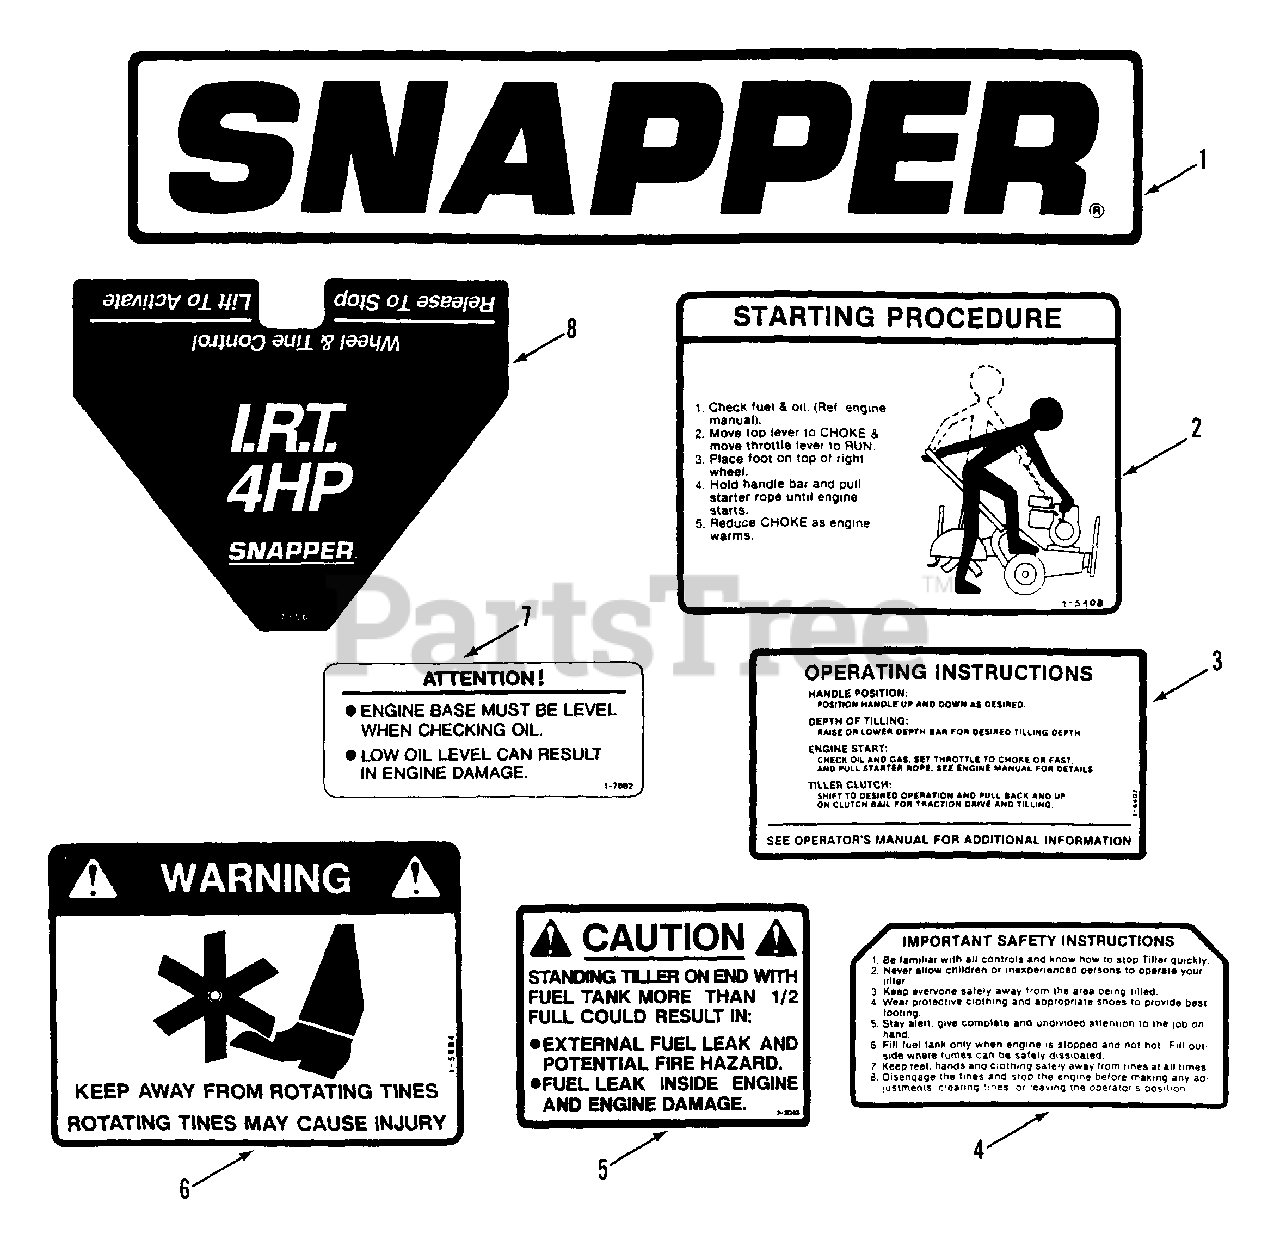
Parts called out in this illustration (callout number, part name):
1	DECAL, SNAPPER
2	DECAL, Starting
3	DECAL, Operating
4	DECAL, Safety
5	DECAL, Caution
6	DECAL, Warning
7	DECAL, Engine Oil
8	DECAL, Control
